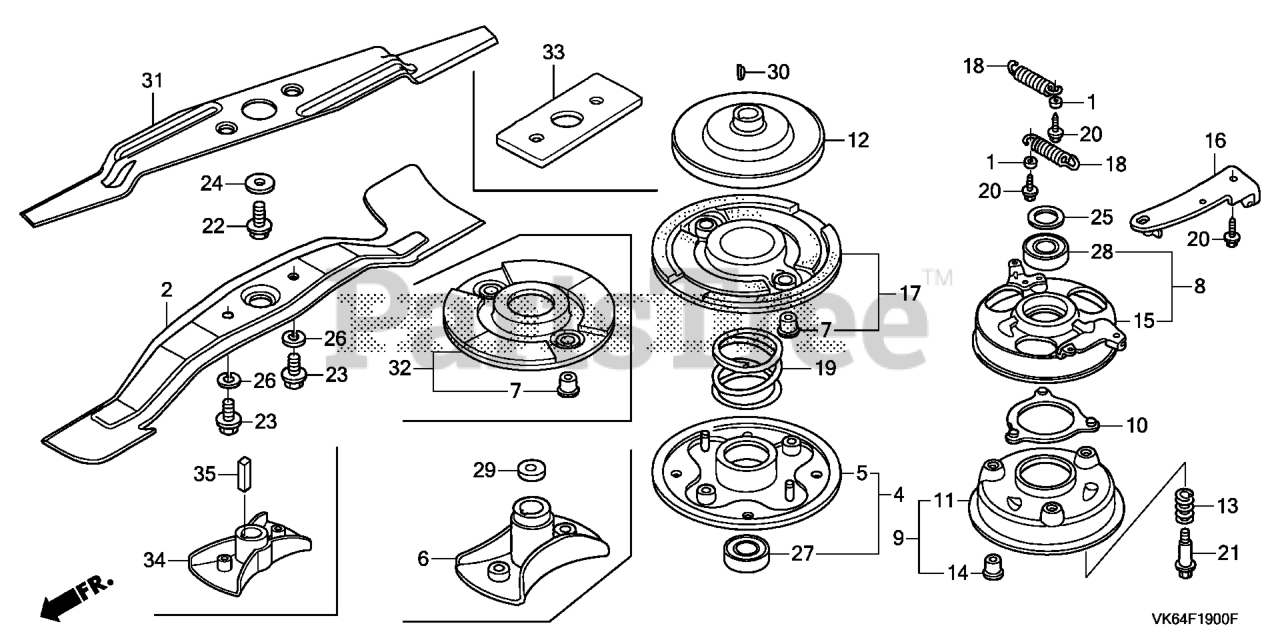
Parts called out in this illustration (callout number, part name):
2	BLADE, ROTARY
6	HOLDER, BLADE
22	BOLT, FLANGE (3/8-24X1-5/16IN)
23	BOLT, HEX. (10X20)
26	WASHER, SPRING (10MM)
29	COLLAR, HOLDER
30	KEY, WOODRUFF (3/16X5/8)
31	BLADE, ROTARY (UPPER)
33	SPACER KIT, BLADE
